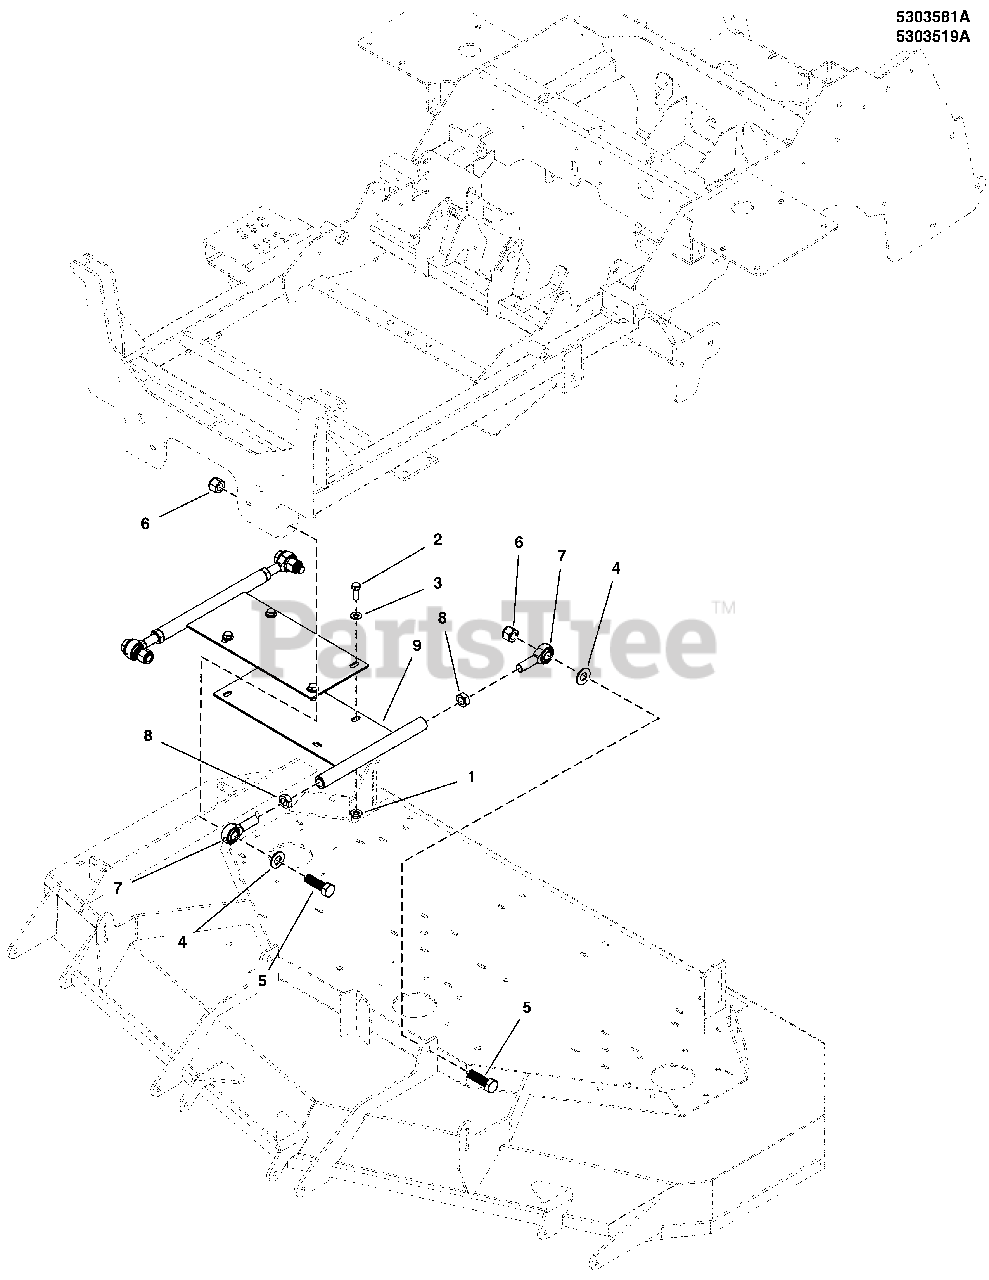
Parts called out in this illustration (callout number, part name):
1	NUT, 3/8-16 HEX SERRA
2	BOLT, 3/8-16 X 1" GD5
3	WASHER, 3/8"
4	WASHER, 5/8" SAE
5	BOLT, 5/8-11 X 2
6	NUT,5/8-11 HEX NYLON
7	BALL JOINT, 5/8-18
8	NUT, 5/8-18 HEX JAM
9	WELD, DECK STABILIZER
